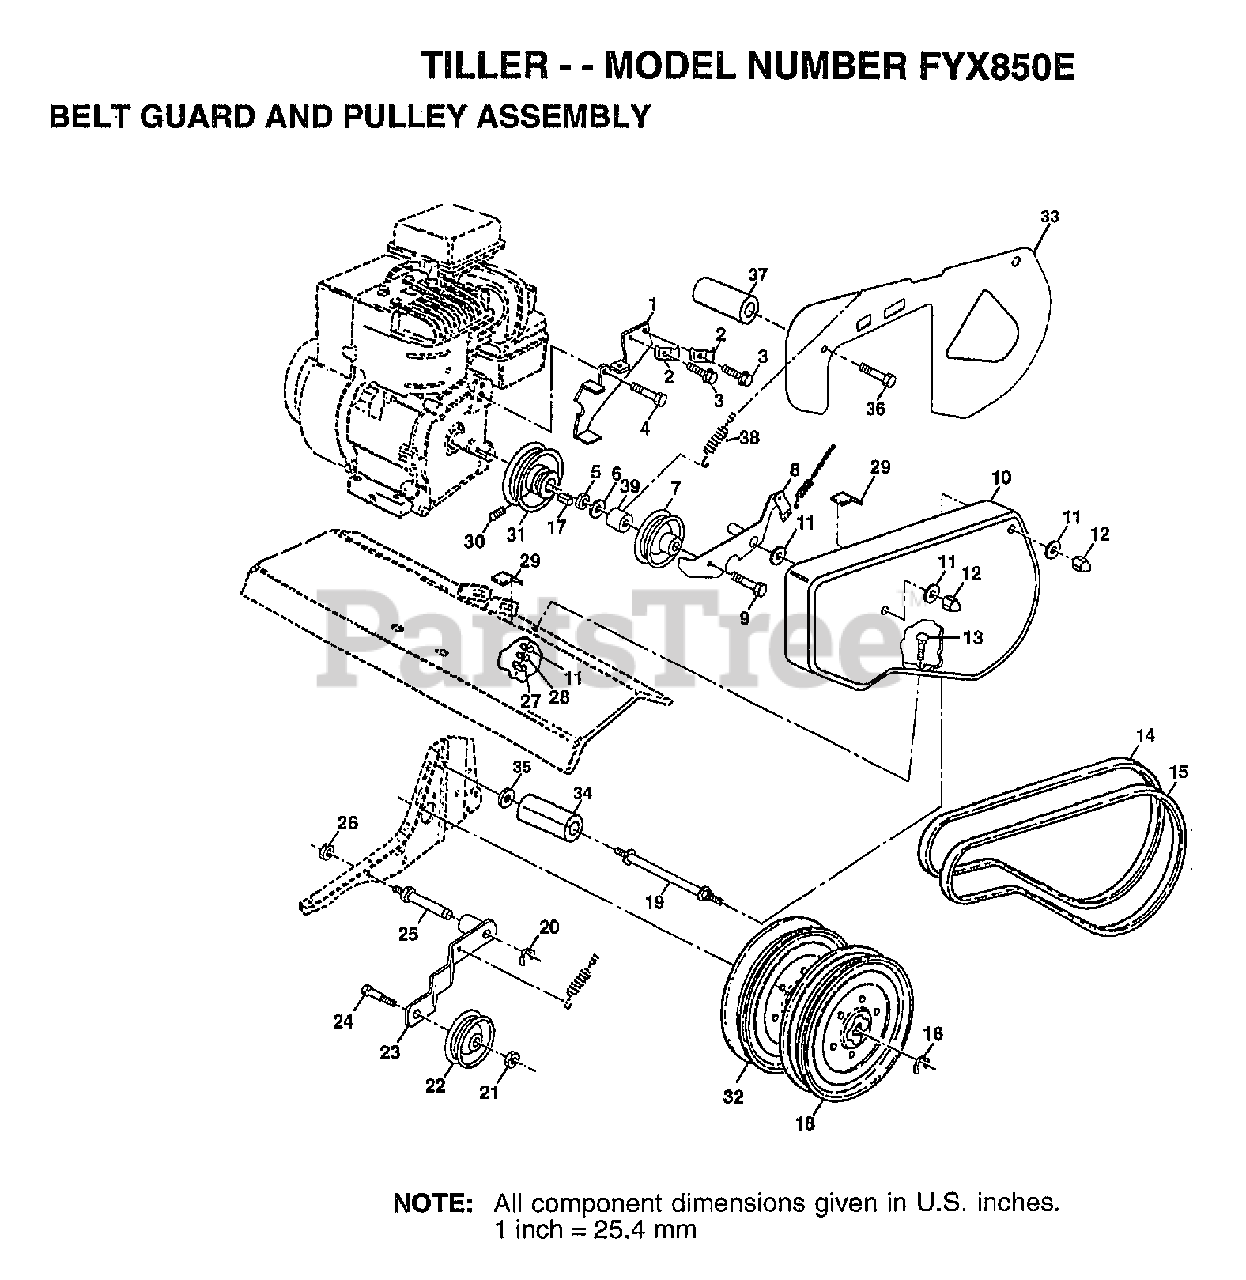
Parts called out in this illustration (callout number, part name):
1	ASSY.BRKT.BELT GUARD
2	CONDIUT CLIP T
4	BOLT.HEX.HEAD
5	NUTLOCK 3/8-16
6	WASHER
7	PULLEY W/SPACER
8	ASSY ARM REV.IDLR
11	WASHER
12	NUT-CAP TI
13	BOLT T
14	BELT-V
17	KEY T
18	SHEAVE.TRANS
19	BOLT TI
20	KLIP RING TI
21	NUT
22	"PULLEY,IDLER"
23	"ARM, IDLER"
25	SHAFT IDLER TI
26	JAM NUT TI
28	LOCKWASHER
29	PAD IDLER TI
30	SET SCREW
31	ENGINE PULLEY TI
32	"SHEAVE,TRANS.""D"""
33	"SHIELD,BELT GUARD"
34	SPACER.SPLIT
35	WASHER
36	BOLT.5/16X24X1
37	SPACER.SPLIT
38	"SPRING,EXT"
39	SPACER.500X384X23
